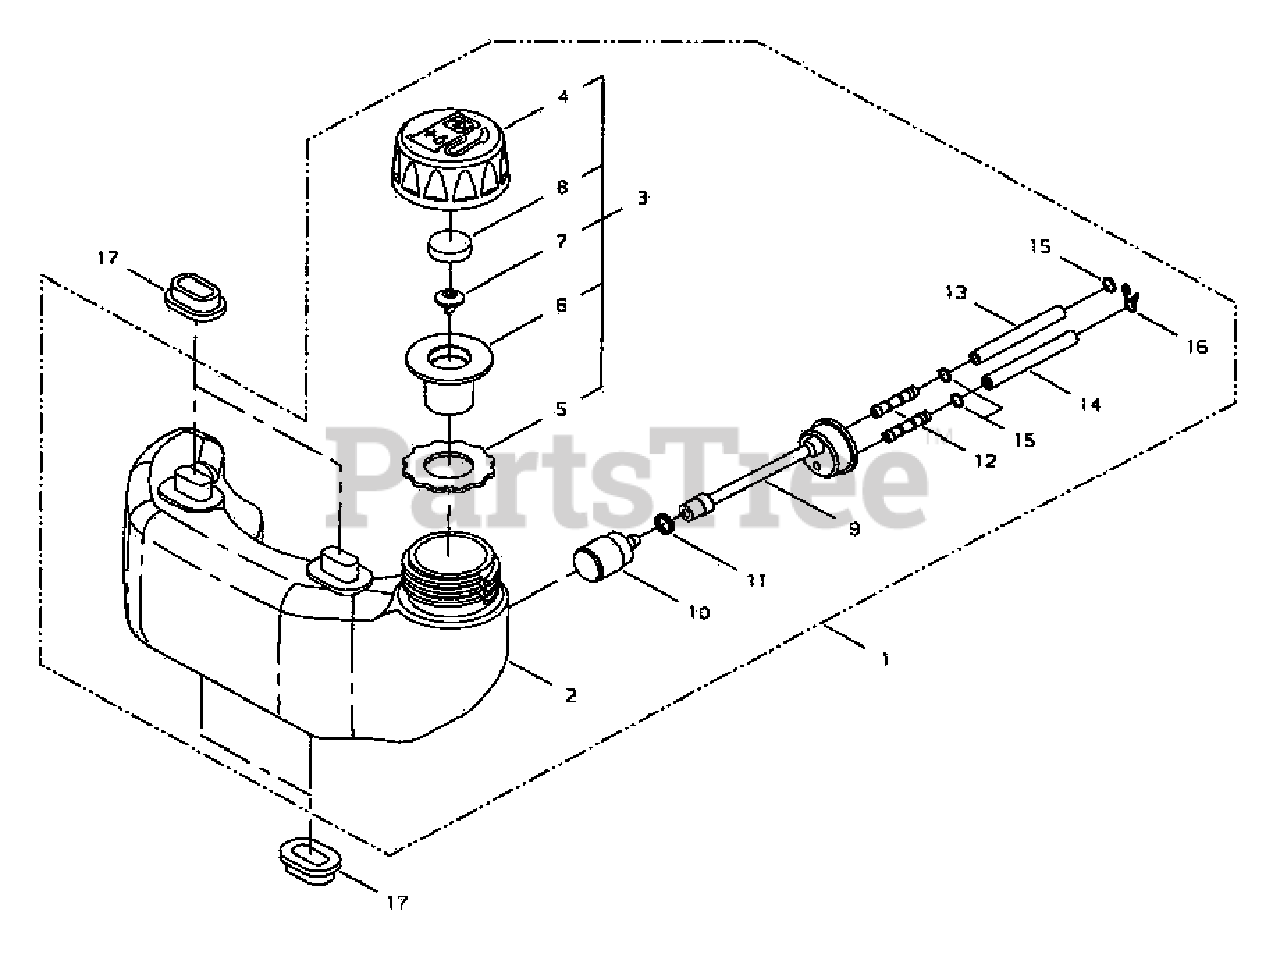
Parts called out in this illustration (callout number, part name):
1	FUEL TANK ASSY
2	TANK, FUEL
3	CAP ASSY, FUEL
4	CAP, FUEL
5	GASKET, FUEL CAP
6	VENT ASSY
7	VENT ASSY
8	PACKING, VENT
9	GROMMET, FUEL WITH PIPE
10	FILTER, FUEL 125-528
11	CLIP
12	CONNECTOR, PIPE
13	PIPE, FUEL
14	PIPE, FUEL RETURN
15	CLIP Ø6
16	CLIP, SPRING Ø5.2
17	CUSHION, FUEL TANK
